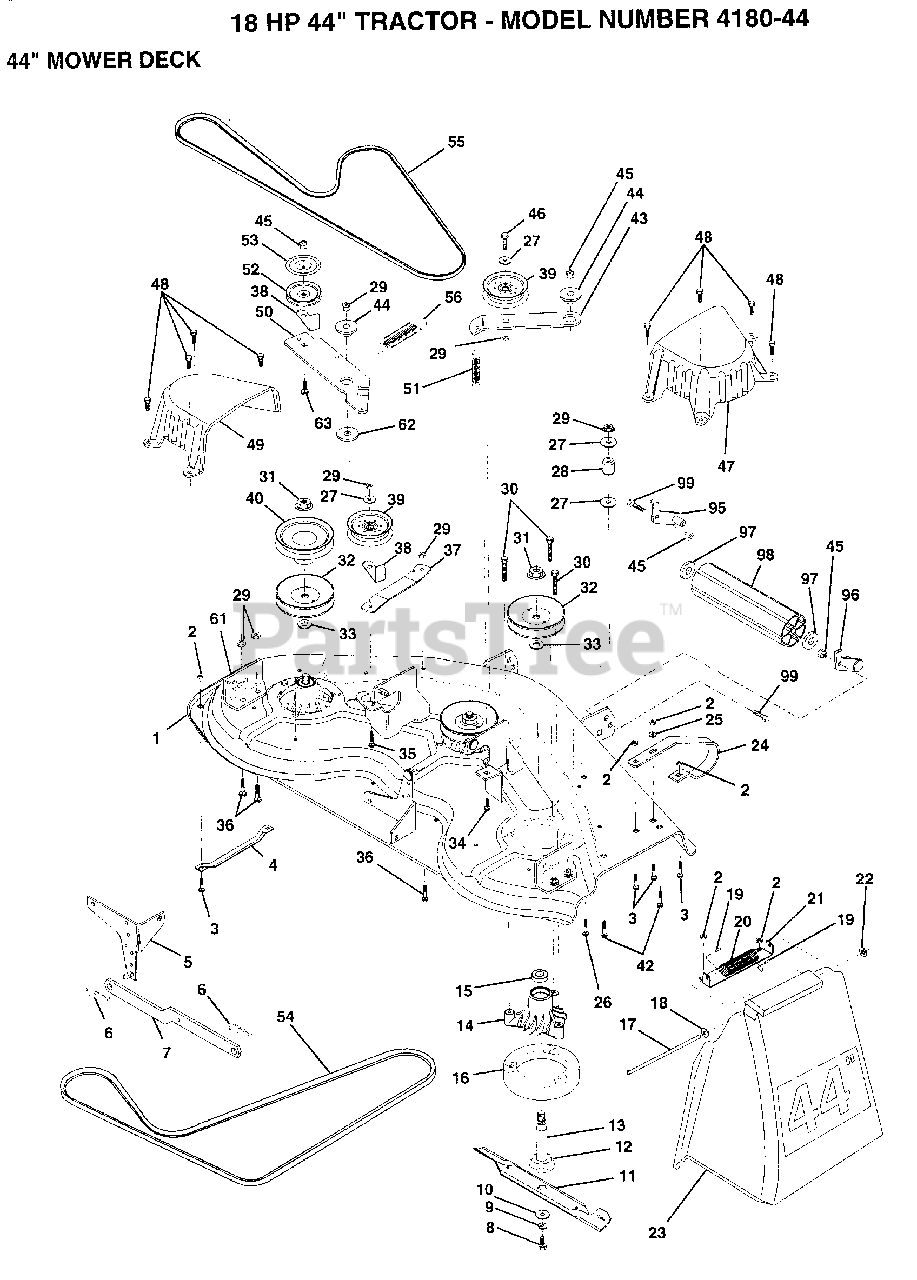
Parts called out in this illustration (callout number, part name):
1	"DECK ASM WELD44"""
2	NUT
4	RUNNER-LH M
5	BRKT.ASM.SW.44/50
8	BLADE BOLT
10	WASHER.HARD.BLADE
11	"BLADE.44"" HIPERF"
12	BEARING.BALL
13	SHAFT.ASM.W/BRNG
14	HOUSING.MAND.44.V
15	BEARING
17	ROD-HINGE T
18	WASHER
19	CAP-SLEEVE LT
20	SPRING TORSION
21	BRKT DEFLECTOR
22	NUT PUSH M
23	DEFLECTOR SHIELD
24	RUNNER.RH
25	WASHER M
26	BOLT
27	WASHER
29	NUT
33	WASHER
34	BOLT.3/8-14X1.25
35	BOLT
36	BOLT D
37	STIFFENER.ARM.IDL
39	FLAT IDLER PULLEY
40	"PULLEY.DRIVEN.44"""
42	BOLT
43	"ARM.IDLER.SEC.44"""
44	SPACER RETAINER
47	"COVER.MAND.RH.44"""
48	SCREW.1/4-20X5/8
49	COVER.MANDREL.LH
50	ARM.IDLER.PRIMARY
51	"SPRING.SEC.44""VEN"
52	PULLEY.IDLER.VGRO
53	SHIELD.IDLER.44.V
54	V-BELT.PRIM.78.5.
55	BELT-V.88.12.MW
56	SPRING.EXT.DECK.
61	BRACKET.GUAGE.WHL
62	HARDENED WASHER
63	BOLT.3/8-16X1.50
64	WASHER
67	LOCKNUT
97	WASHER
99	BOLT
